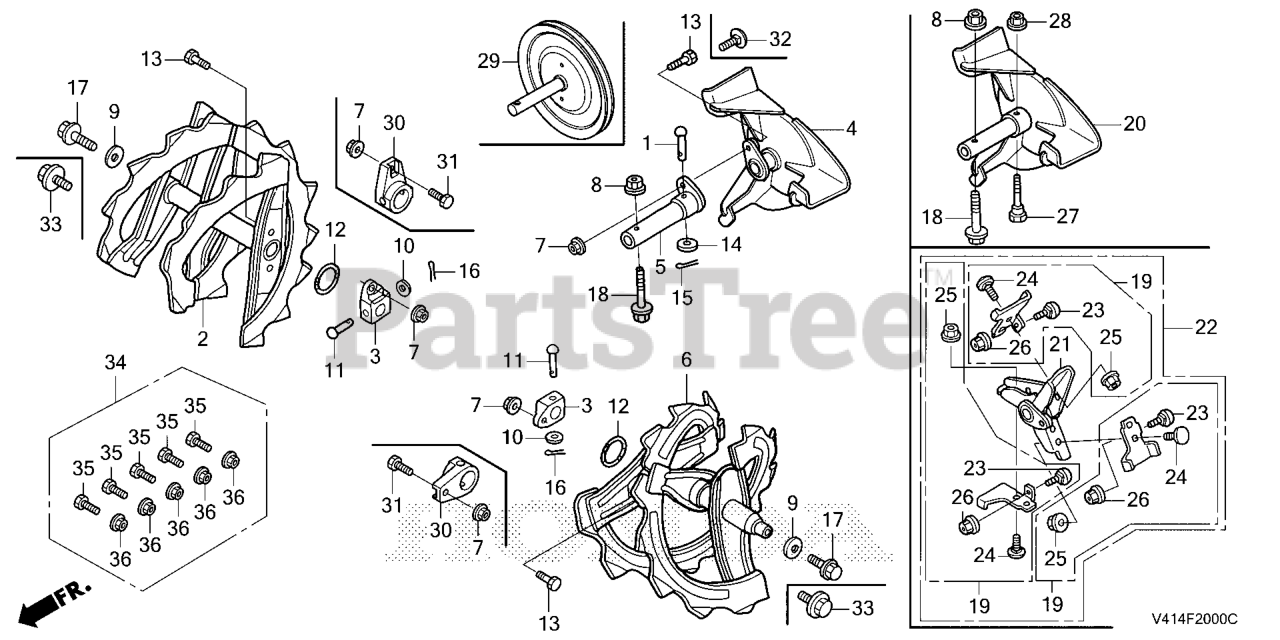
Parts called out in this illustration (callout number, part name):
1	PIN (10X41)
3	BOSS, LOCK BOLT
5	PIPE, JOINT
7	NUT, SELF-LOCK (6MM)
8	NUT, FLANGE (8MM)
10	WASHER, PLAIN (7MM)
11	PIN (7X40)
12	O-RING (18.23X1.9)
14	WASHER, PLAIN (10MM)
15	PIN, SPLIT (3.0X25)
15	PIN, COTTER (3.0X45)
16	PIN, SPLIT (3.0X25)
16	PIN, COTTER (3.0X45)
18	BOLT, FLANGE (8X45)
29	PULLEY, DRIVEN
30	BOSS, LOCK BOLT
31	BOLT, SPECIAL (6X18)
32	BOLT, CARRIAGE (6X18)
33	BOLT, FLANGE (8X14)
34	BOLT KIT
35	BOLT, SPECIAL (6X18)
36	NUT, SELF-LOCK (6MM)
